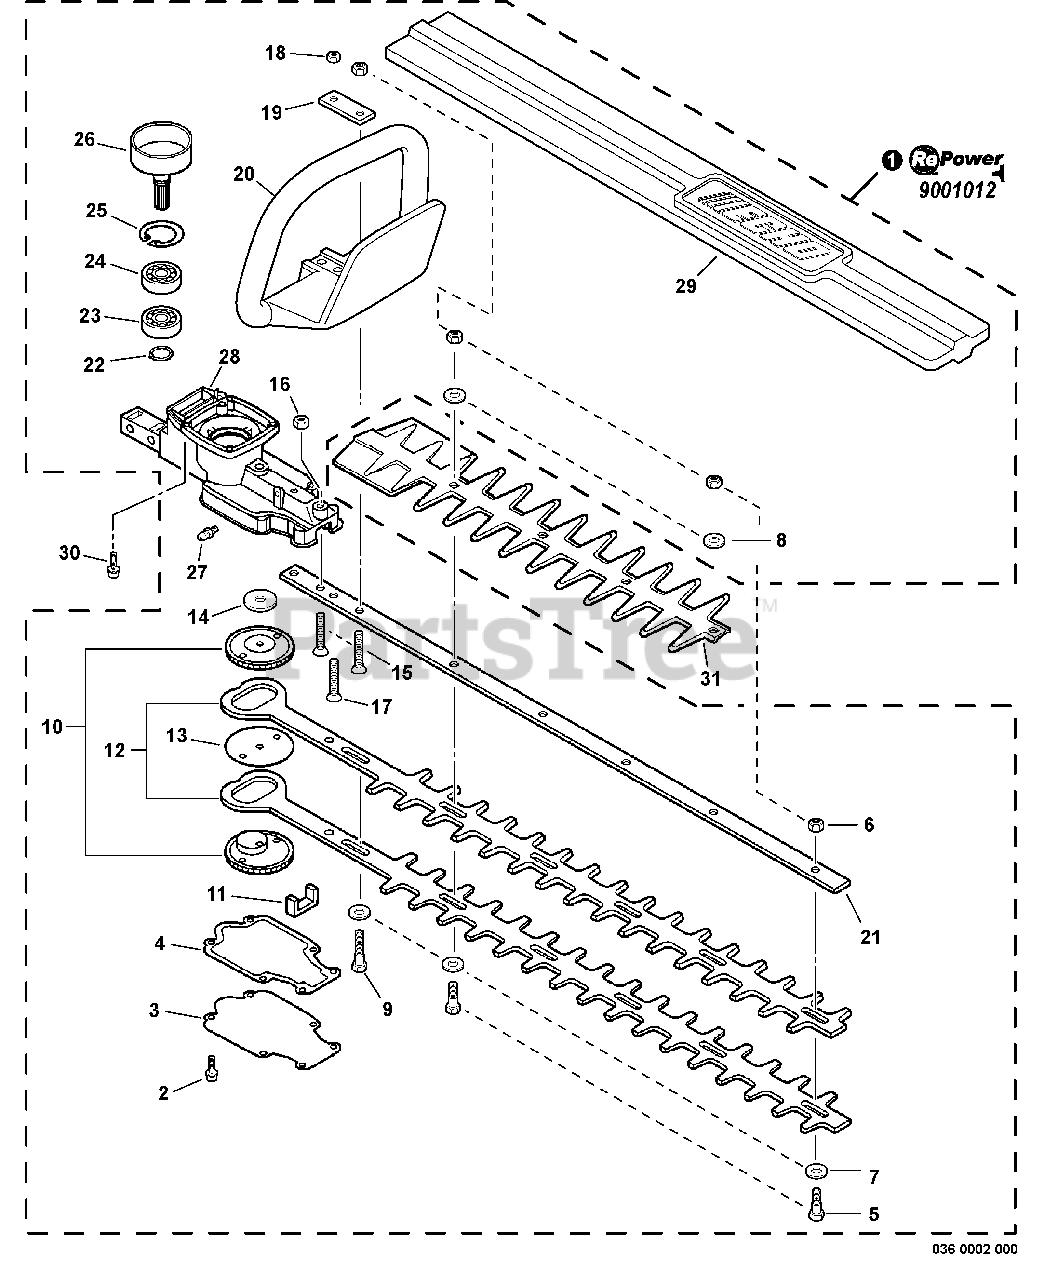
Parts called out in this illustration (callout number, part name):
1	CUTTING HEAD KIT
2	BOLT 4×12
3	COVER, GEAR CASE
4	GASKET, GEAR CASE
5	BOLT 6×18
7	WASHER 6.5×15.5×0.6
8	WASHER 6.5×15.5×0.6
9	BOLT M6×35
10	GEAR, SPUR
12	CUTTER
13	WASHER 6.7×54×0.38
14	WASHER 6.5×30×0.2
15	SCREW 6×30
16	NUT, HEX M6
17	SCREW 5×30
18	NUT, LOCK M5
19	PLATE, EYE
20	HANDLE, SUPPORT
21	SUPPORT, BLADE
22	RING, SNAP 14
23	BEARING, BALL 6202
24	BEARING, BALL 6202
25	RING, SNAP 35
26	DRUM, CLUTCH
27	FITTING, GREASE
28	CASE, GEAR
29	SCABBARD 23.6"
30	BOLT 4×16
31	GUARD, CUTTER BLADE
